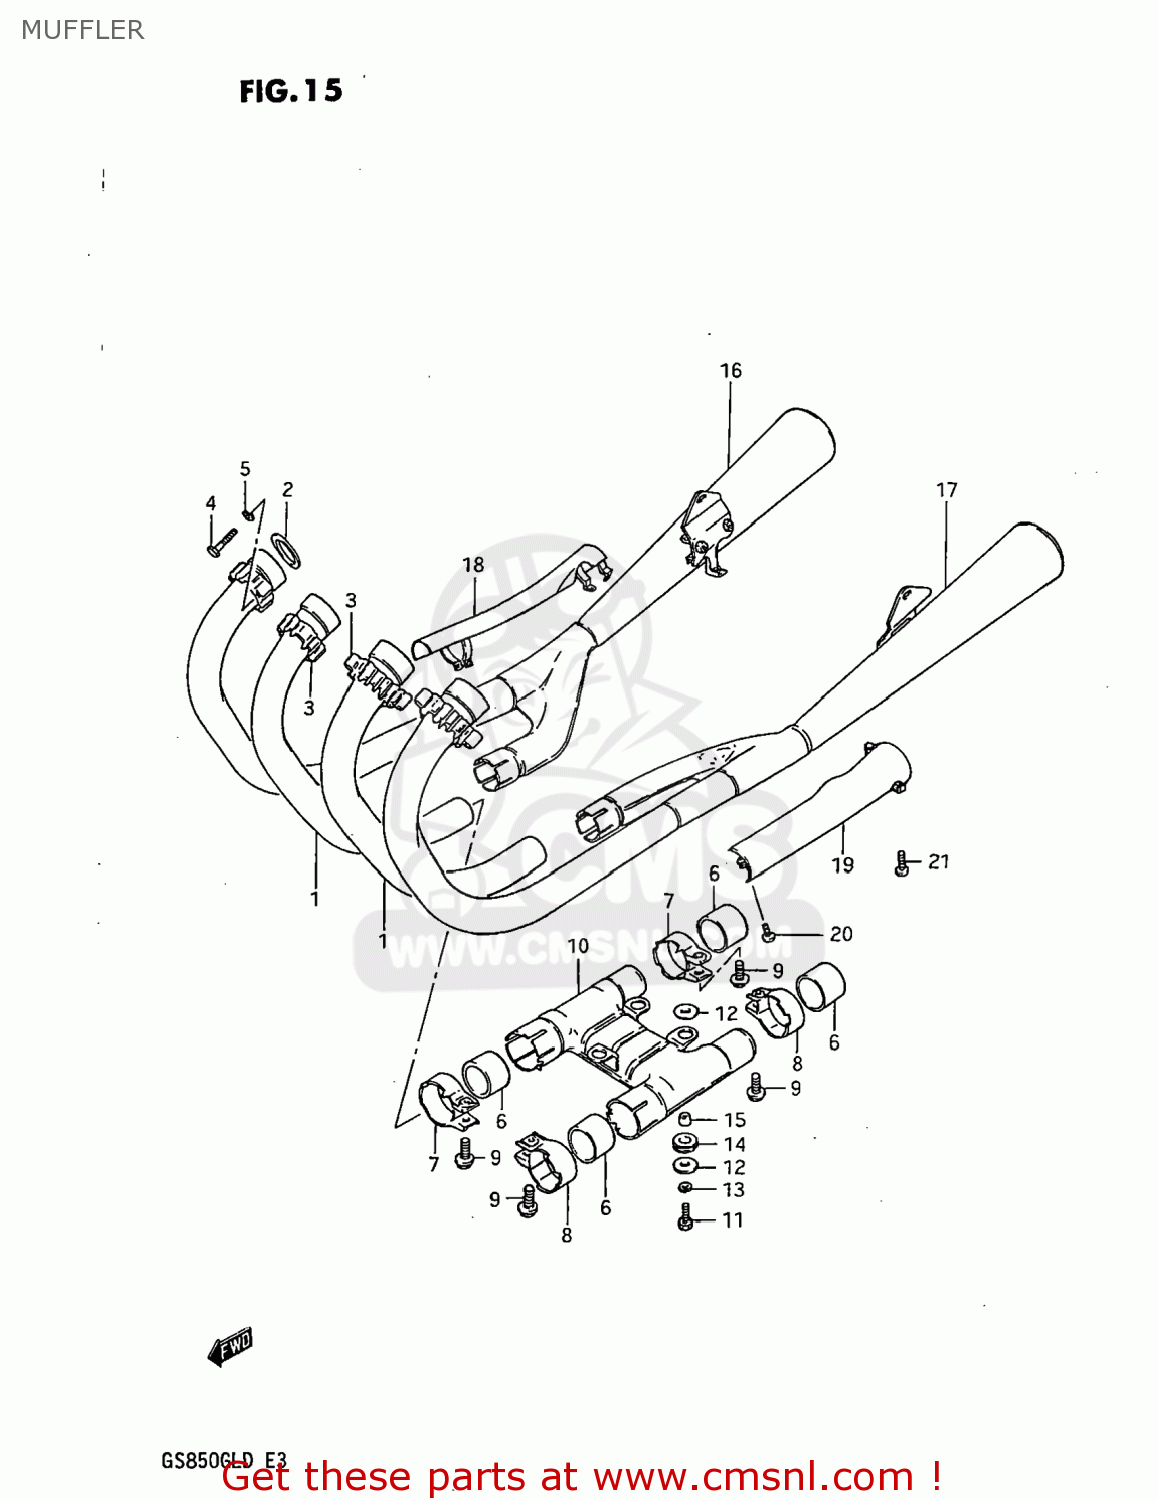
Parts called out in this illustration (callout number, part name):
1	PIPE,CENTER EXHAUST
2	GASKET,EXHAUST PIPE (NAS)
3	CLAMP,EXHAUST PIPE
4	BOLT
5	LOCK WASHER
6	CONNECTOR,MUFFLER
7	CLAMP,MUFFLER CONNECTOR,R
8	CLAMP,MUFFLER CONNECTOR,L
9	BOLT
10	BODY,PREMUFFLER
11	BOLT
12	WASHER (6.5X24X1.6)
13	LOCK WASHER
14	CUSHION
15	SPACER(6.5X10.5X6.5)
16	MUFFLER ASSEMBLY
17	MUFFLER ASSEMBLY
18	COVER,MUFFLER,R
19	COVER,MUFFLER
20	SCREW
21	SCREW
